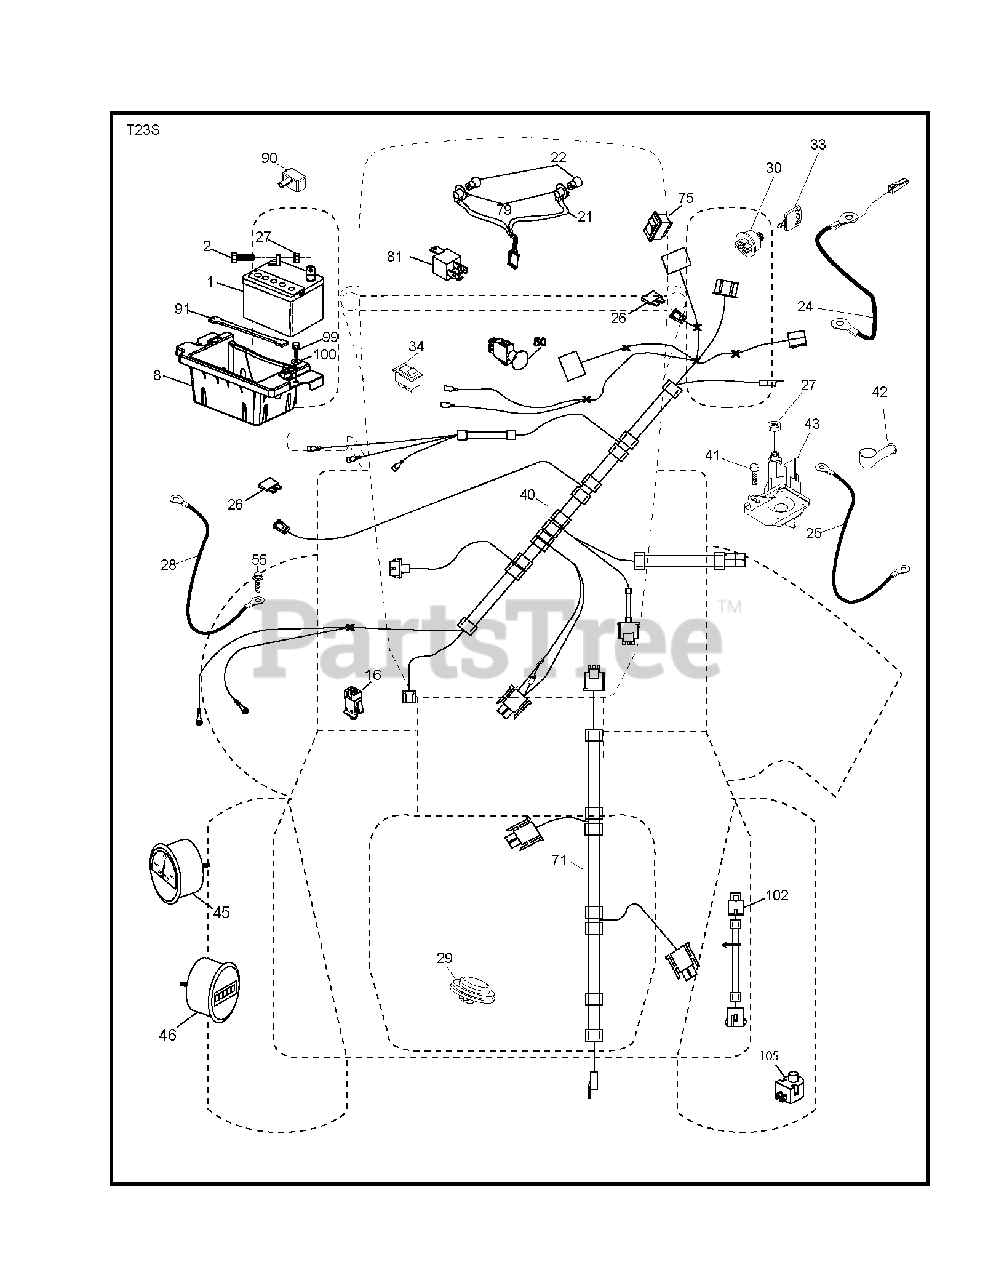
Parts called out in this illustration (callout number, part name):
1	REPL BY 532 12 38-99
2	BOLT.HEX.1/4.X.3/4.DICHROMATE
8	BOX.BATTERY.MOUNT.FRONT.LT
16	SWITCH INTERLOOK PUSH-IN
21	HARNESS.W/LIGHT SOCKET
22	LIGHTBULB
24	CABLE.BATT.POS.WIRE.TG.DA SOL
25	CABLE.STARTER.6G.BL/RED.17.5
26	FUSE 20AMP
27	NUT
28	CABLE GROUND 6 GA 21" 90T BLK
29	SWITCH.SEAT.DELTA.OPC.
30	SWITCH.IGN.DELTA.W.LGH.ROS
33	KEY.CHAIN.BLISTER.PACK.GEN.USA
34	SWITCH LT
40	HARNESS.DASH.ELECTRIC.LIFT
41	SCREW
42	TERMINAL COVER
43	SOLENOID.W/BRASS.PLUNGER
45	AMMETER.ROUND.SNAPIN
46	HOURMETER.ROUND.SNAPIN
55	SCREW 5/16"
71	HARNESS
75	SWITCH.ROCKER.DECKLIFT
79	BULB HOLDER ASM.
81	RELAY HARNESS.SEALED
90	COVER.TERMINAL.BATTERY
91	STRAP.BATTERY.MOUNT.FRONT
99	SCREW HEXWSHR 1/4-20X3/4
102	HARNESS PIGTAIL PCH TEX ROS
105	REVERSE SWITCH
